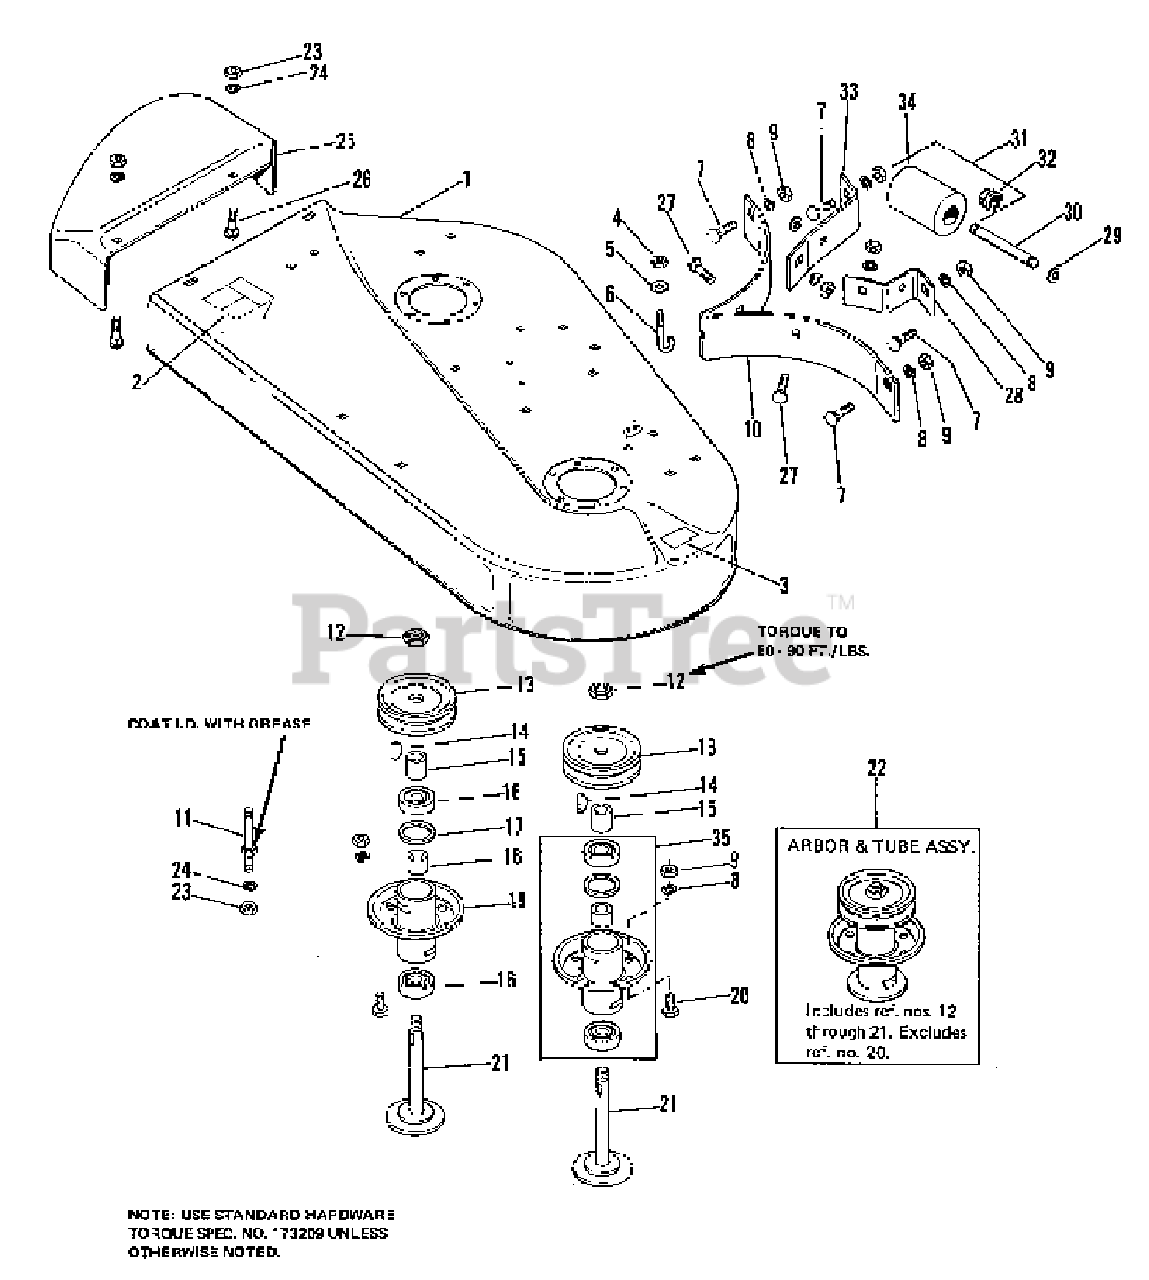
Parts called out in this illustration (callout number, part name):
1	DECK, Mower
2	DECAL, Caution, OPEI
3	DECAL, Caution
4	NUT, Hex, Full, Lock, 1/4-20
5	WASHER, Plain, 1/4
6	SCREW, Baffle Hook
7	BOLT, Carriage, Short Neck, 5/16-18 x 3/4
8	LOCKWASHER, 5/16
9	NUT, Hex, Full, 5/16-18
11	STUD, 2-5/8
12	NUT, Full, Jam, 3/4-16
14	KEY, No. 61, Woodruff
16	BALL, Bearing
17	RING, Backing
19	ARBOR TUBE ASSEMBLY
20	CAPSCREW, 5/16-18 x 3/4
21	ARBOR ASSEMBLY
22	ARBOR & TUBE ASSEMBLY
23	NUT, Hex, 3/8-16
24	LOCKWASHER, 3/8
25	DEFLECTOR, Mower
26	BOLT, Carriage, 3/8-16 x 3/4
27	BOLT, Carriage, 5/16-18 x 5/8
28	BRACKET, L.H., Roller
29	RING, "E"
30	SHAFT, Center Roller
31	ROLLER ASSEMBLY
33	BRACKET, R.H., Roller
35	TUBE & BEARING ASSEMBLY
